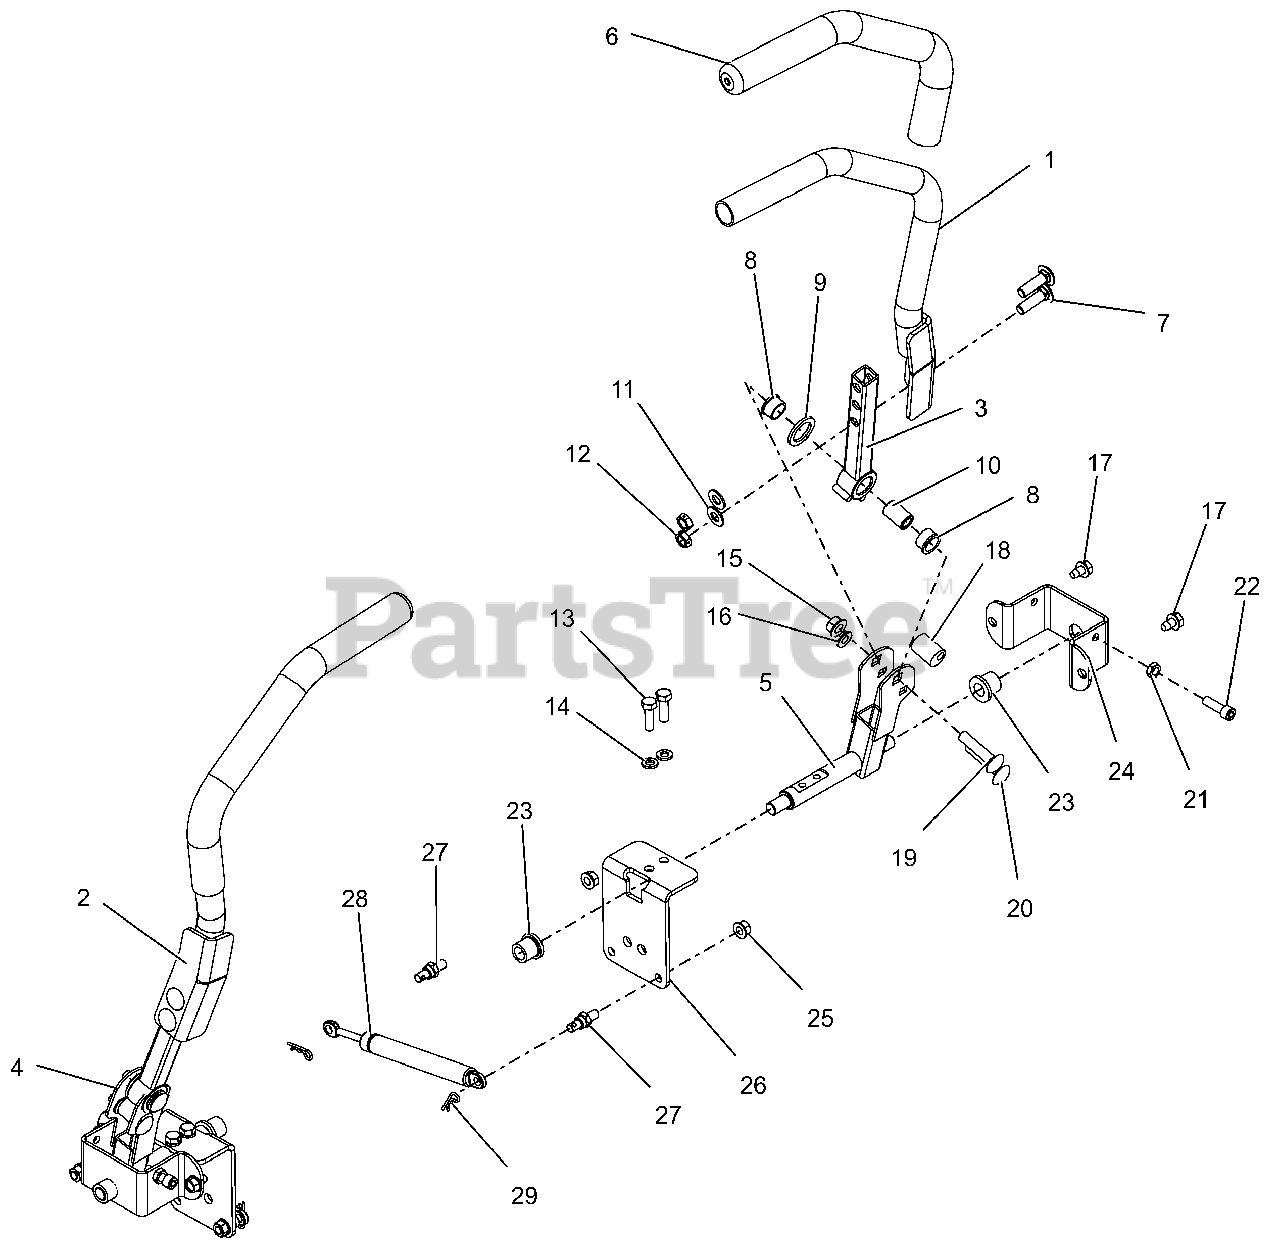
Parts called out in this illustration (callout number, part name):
1	WLDMT, STEERING HANDLE LH
2	WLDMT, STEERING HANDLE RH
3	WLDMT, UPPER CONTROL ARM
4	WLDMT,STEERING ARM LOWER RIGHT
5	WLDMT,STEERING ARM LOWER LEFT
6	GRIP, HANDLEBAR 15" FOAM
7	BLT,RHSSN-.375X1.25 G5 RIE5230
8	BSHG-FLG, .625X.75X.450X.875
9	WASHER, FRICTION .875X1.25X.10
10	SPACER, .375X.625X.970 (PM)
11	WSHR,FLT .406X.812X.065 ZCC
12	@NUT-LK-CTR-JAM .375-16 YWZC
13	BLT, HEX .31-18X1.00 G8 ZCC
14	WSHR,LK-REG .312X.078 ZCC
15	NUT-LK-CTR-FLG .375-16 GF ZCC
16	NUT,NYL-FLG .31-18 GF ZCC
17	SCR,TAP .312-18X.50 HWH TR ZCC
18	BSHG,ECCEN .328X.750X1.01 PM
19	BLT,RHSSN-.375X1.75 G5 RIE5230
20	BLT,RHSSN-.312X1.75 G5 RIE5230
21	NUT-JAM .312-18 G2 ZCC
22	SCR, SKH .312-18X1.00 G8 ZC120
23	BSHG-FLG .515X.750X.745X1.00NY
24	BRKT, STEERING
25	NUT-LK-TOP-FLG .312-18 GF ZCC
26	BRKT, STEEERING
27	COUPLER, DAMPER MOUNT
28	DAMPER, STRAIGHT MOUNT
29	PIN, HAIR #213 .08X1.19 ZCC
